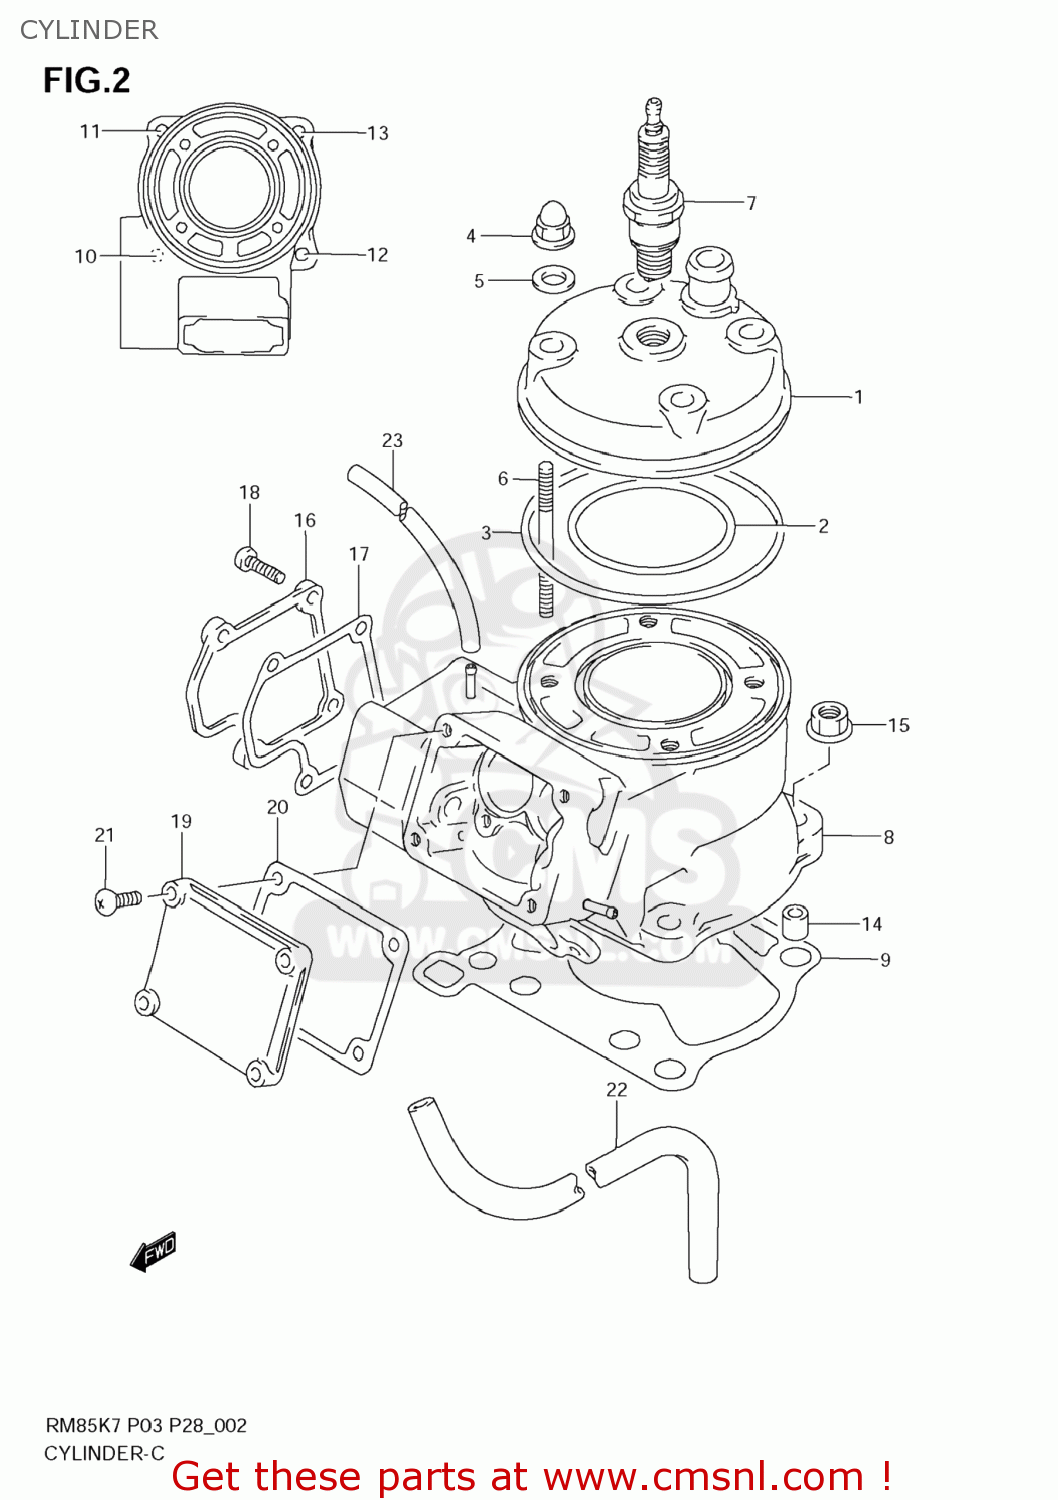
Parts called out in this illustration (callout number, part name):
1	HEAD,CYLINDER
2	O RING,CYLINDER HEAD NO.1
3	O RING,CYLINDER HEAD NO.2
4	NUT
5	GASKET(8.5X17X2.3) (NAS)
6	BOLT,STUD
7	PLUG,SPARK(BR10ES)
8	CYLINDER SET
9	GASKET,CYLINDER (NAS)
10	BOLT,STUD
11	BOLT,STUD
12	BOLT,STUD
13	BOLT,STUD
14	PIN(8.4X11X14)
15	NUT
16	COVER,CYLINDER NO.1
17	GASKET,CYLINDER COVER NO.1 (NAS)
18	BOLT(5X16)
19	COVER,CYLINDER NO.2
20	GASKET,CYL COVER NO.2 (NAS)
21	BOLT(5X16)
22	HOSE(5X8.2X600)
23	HOSE(5X8.2X600)
